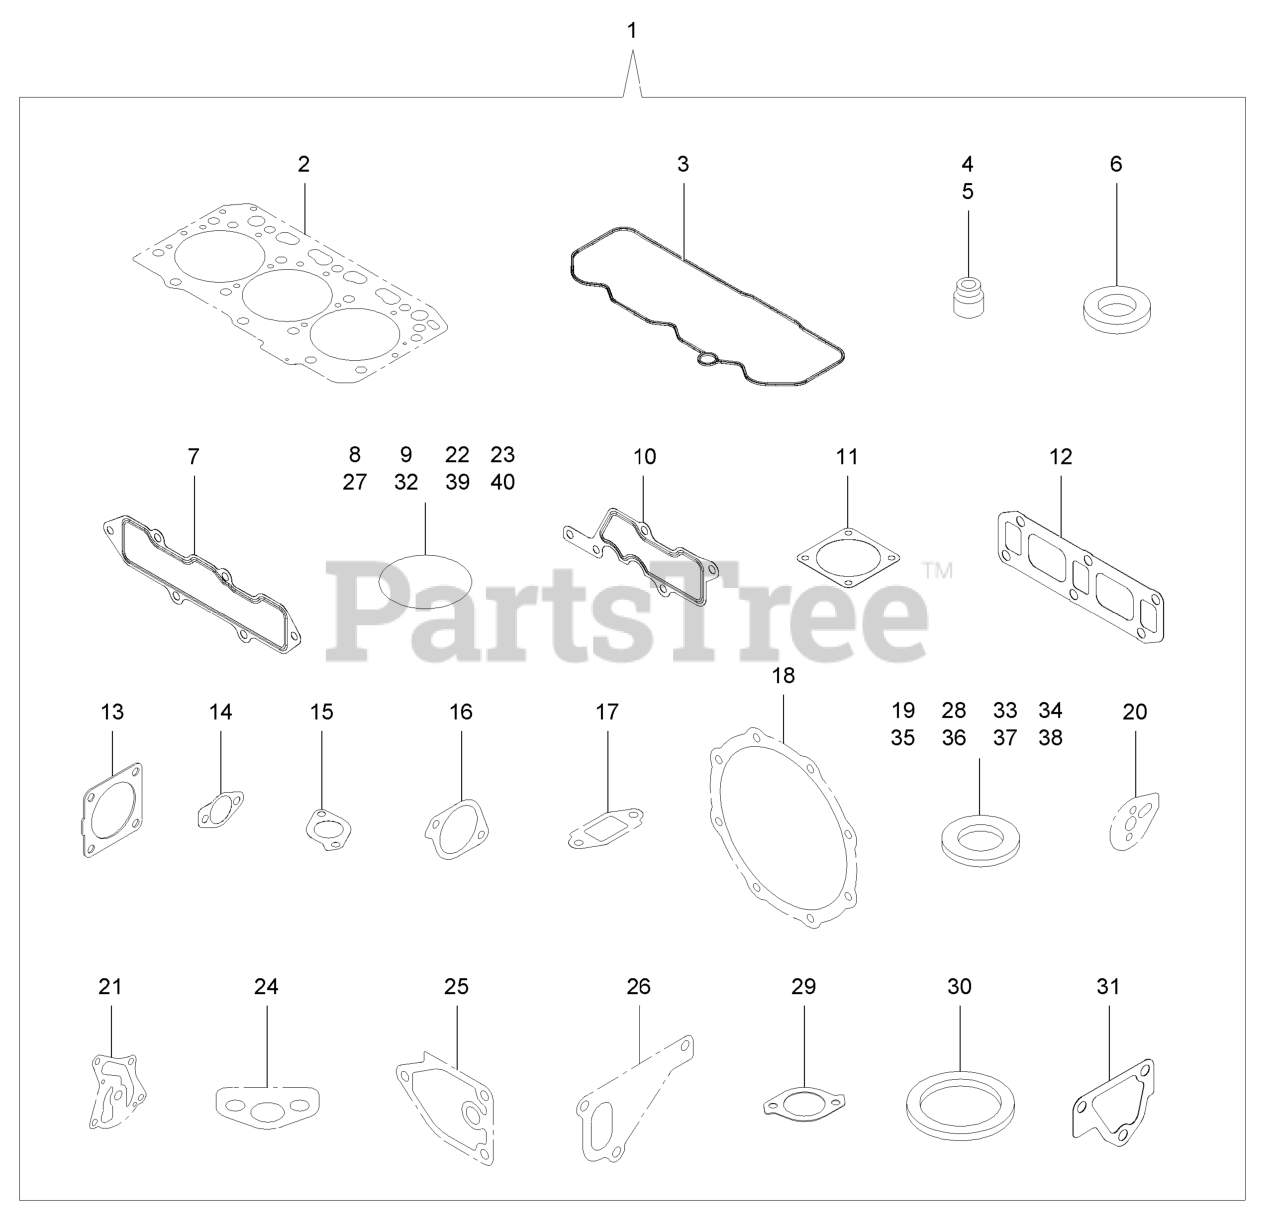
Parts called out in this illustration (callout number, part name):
1	Packing (Gasket Set)
2	Head Gasket ASM
3	Gasket-Head, Cylinder
4	Seal-Stem, Valve
5	Seal-Stem, Valve
6	Gasket-Injector
7	Gasket-Manifold, Intake
8	O Ring-Sensor, Pressure
9	O Ring-Sensor, Temp
10	Gasket-Collector
11	Gasket-Throttle
12	Gasket-Manifold, Exhaust
13	Gasket-Silencer
14	Gasket-Cooler, E G R
16	Gasket-Intake Valve, E G R
17	Gasket-Out Valve, E G R
18	Gasket-D P F
19	Gasket-Sensor
20	Gasket-Idle, Shaft B
32	O Ring-Pump, Fuel
33	Washer-Seal
34	Washer-Seal
35	Washer-Seal
36	Washer-Seal
